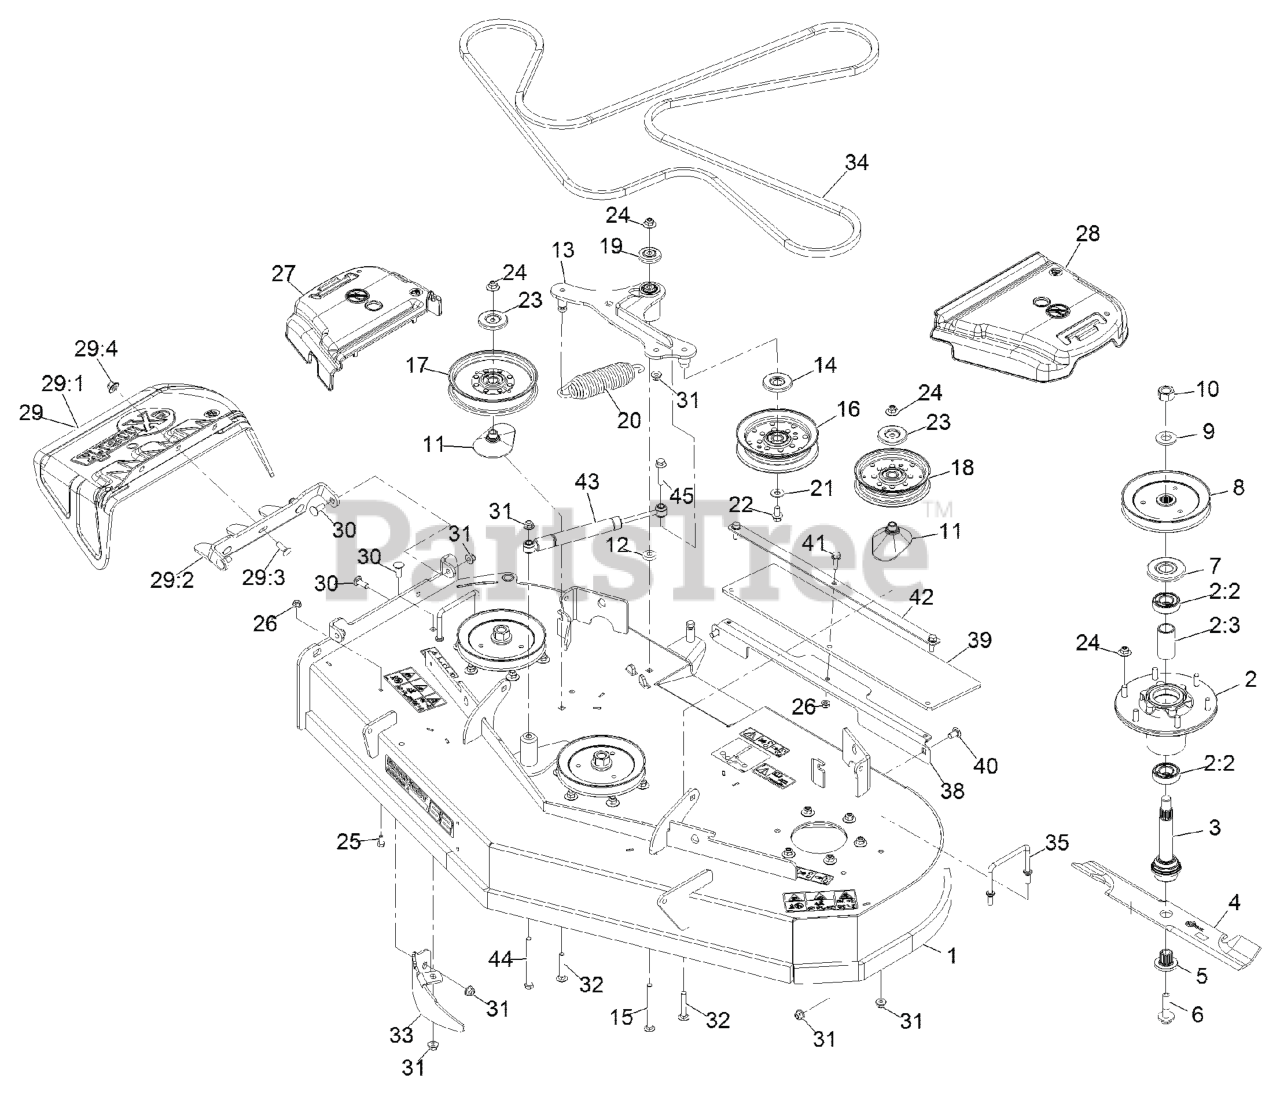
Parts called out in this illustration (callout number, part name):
1	ASM, DECK W/ DECALS, 52
2	ASM-CUTTER HSG WITH BEARINGS
2:2	BEARING-BALL
2:3	SPACER-BEARING
3	ASM-SPINDLE AND SEAL
5	BUSHING,SPLINED
6	SCREW,SEMS 1/2-20 X 2.19
7	GUARD,BEARING TOP .989
8	SHEAVE,BLADE DRIVE 6.50
10	NUT-HEX
11	SPACER-PULLEY
13	ASM-DECK IDLER
14	SHIELD-GUARD, DUST
15	SCREW-CARR
16	IDLER-PULLEY, FLAT
17	IDLER-PULLEY, FLAT 6.00X1.00
18	PULLEY-IDLER, FLAT
19	GUARD-TOP
20	SPRING-EXTENSION
21	WASHER-FLAT
22	SCREW-HHF
23	SHIELD-DUST
24	Nut-Nyloc 3/8-16 Flg
25	SCREW-HH
26	NUT-HF, NI
27	COVER-BELT, RH
28	COVER-BELT, LH
29	ASM,DISCHARGE CHUTE
29:1	CHUTE,DISCHARGE
29:2	BRACKET,DISCHARGE CHUTE
29:3	SCREW-CARR
29:4	Nut-Nyloc 3/8-16 Flg
30	SCREW-CARR
31	NUT-HF, NI
32	Bolt-Carriage 3/8-16 X 2 1/4
33	BAFFLE-DOGLEG, LZ-VT52
34	BELT, 5V
35	WIREFORM-COVER
38	BRKT, HEAT DEFLECTOR
39	SHIELD, HEAT
40	SCREW-CARR
41	SCREW-HHF
42	BRKT-HEAT DEFLECTOR, TOP
44	SCREW-HH
45	SCREW-HHF
